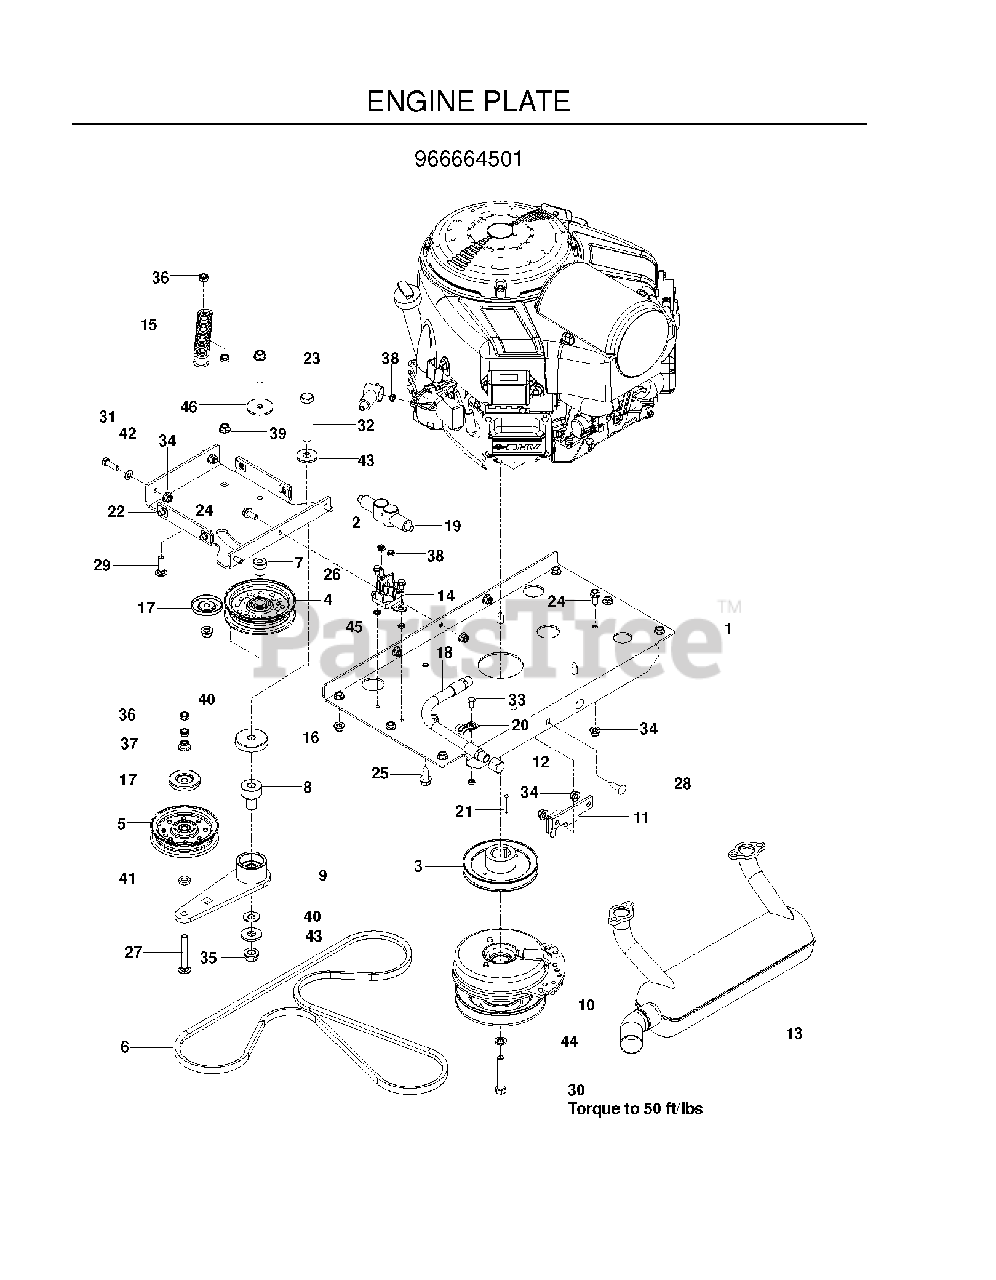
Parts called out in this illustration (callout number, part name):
2	PLATE, IDLER, BLK
3	PULLEY, V, 1.125 BORE
4	IDLER PULLEY
6	BELT, HYDRO, 3400
7	PIVOT, IDLER
8	PIVOT, BEARING
9	ARM, IDLER, STEEL, W/BGS
10	CLUTCH, 200 FT-LB
12	DRAIN CAP
14	SOLENOID
15	SPRING, PUMP
16	SHIELD, DUST
17	DUST SHIELD
18	OIL DRAIN HOSE
19	INSULATOR
21	KEY, 1/4 SQ X 1 1/4
22	U-CLIP 5/16-18 NUT RETAINER
23	HHFS 3/8-16 X 2.0 GD 5
24	HHFS 5/16-18 X 3/4
25	HHFS 3/8-16 X 1.0 THD FORMING
26	HWST 1/4C X 3/8
27	RHSNB 3/8-16 X 2.75
28	RHSSNB 5/16C X 1.0
29	RHSNB 3/8-16 X 1-1/4
30	BOLT 7/16F X 2 1/2
31	HCS 5/16C X 1
32	HCS 1/2C X 3 1/4
33	HCS 1/4-20.
34	5/16-18 NYLOC FLANGE NUT
35	NUT, 1/2-13 HEX FLG NYLOC ZD
36	NUT HEX 3/8-16 NYLON, THIN
37	NUT 3/8-16 HEX FLG NYLOC ZD
38	JAM NUT 1/4C
39	NUT 3/8C WHIZ
40	CONTACT BELLSPR 1/2
41	WASHER 3/8 X 3/4 X .187 TK
42	FLAT WASHER 5/16 SAE
43	WASH USS FLAT 1/2
44	WASHER 7/16 LOCK
45	WASHER 1/4 INT TOOTH
46	WASHER, 3/8 SPEC
